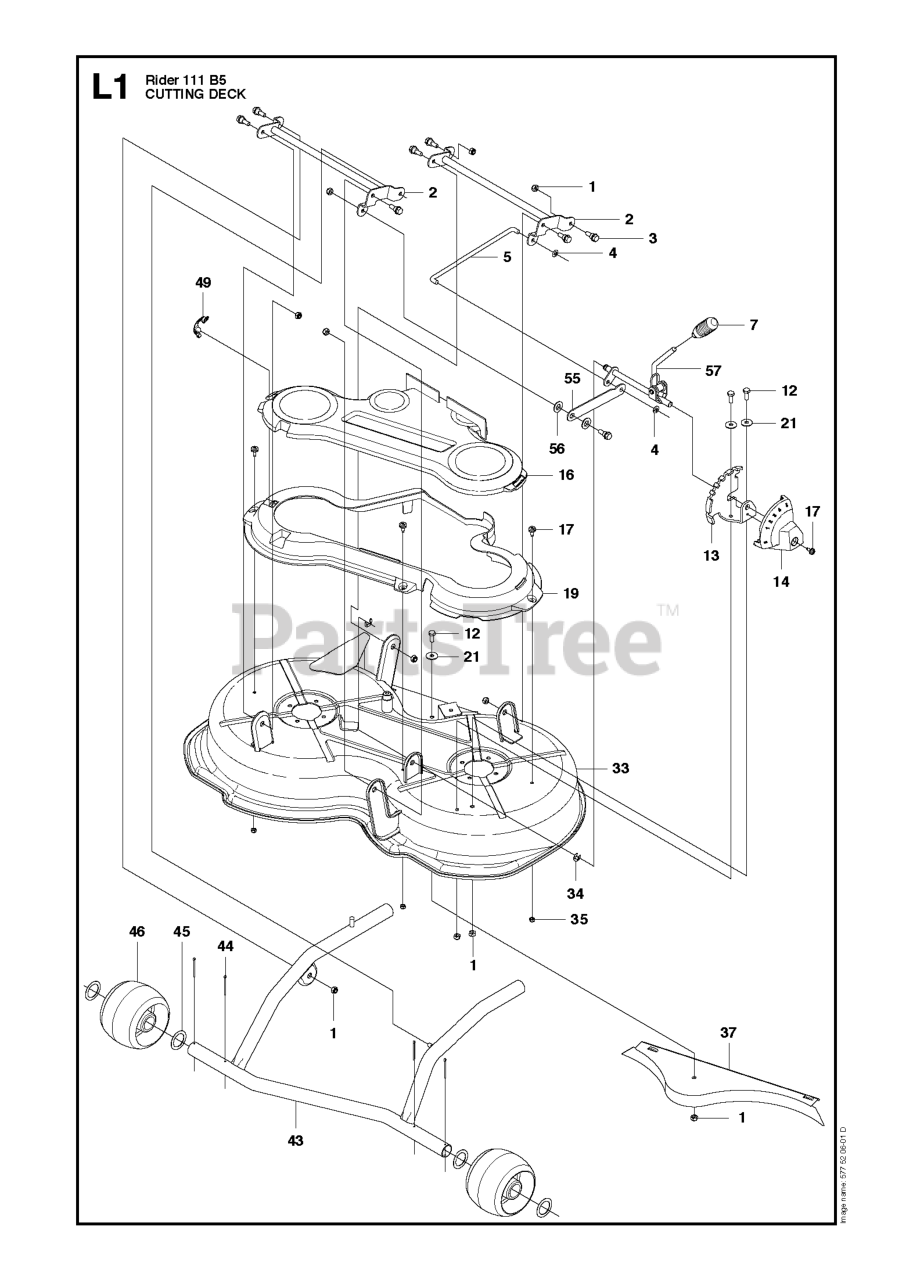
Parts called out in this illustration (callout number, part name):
1	LOCKNUT M8
21	WASHER
34	RETAINING RING
35	LOCKNUT M6
44	COTTER PIN
49	BUCKLE ORANGE
56	WASHER - 25X8.5X2.3
